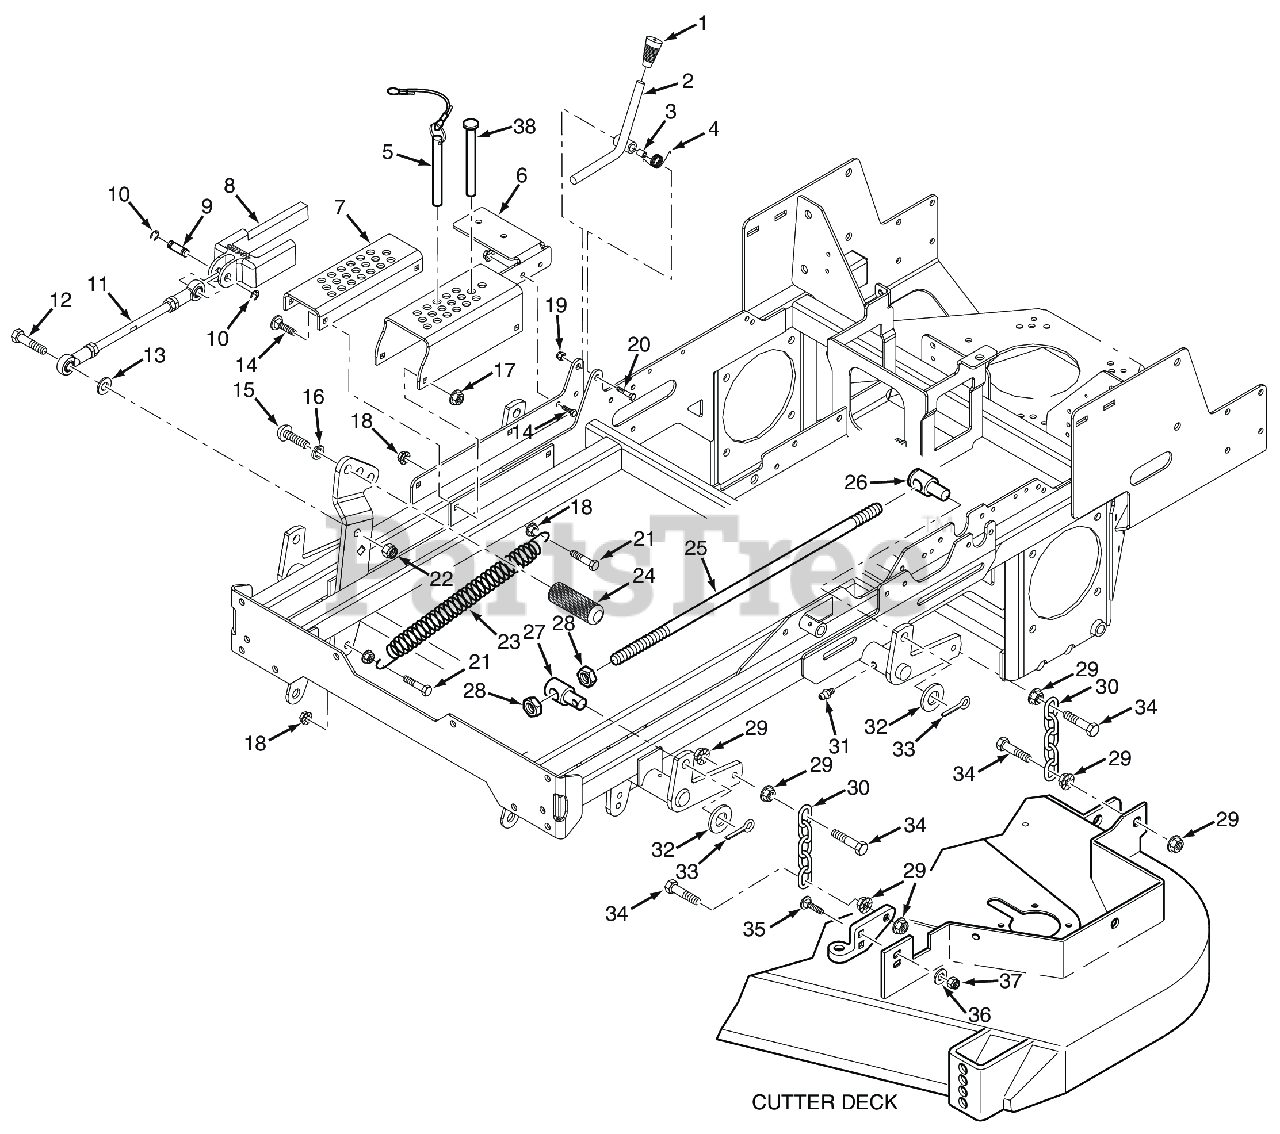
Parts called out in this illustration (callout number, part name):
1	Mounting Bracket, Fuel Tank
2	Deck Latch Assembly w/Grip
3	Bushing, .502 O.D.
4	Spring, Torsion - Lever Return
5	Lanyard, Deck Height Pin Assembly
6	Adjustment Bracket, Upper Cut Height
7	Adjustment Bracket, Lower Cut Height
8	Slide, Height Adjustment
9	Pin, Deck Lift
10	Retaining Ring, 1/2" External "E"
11	Linkage, Deck Lift
11	Rod End, 1/2-20 Female RH Thread
11	Rod End, 1/2-20 Female LH Thread
11	Nut, 1/2-20 UNF-2B RH Thread
11	Bolt, Hex Hd. 5/16-18 x 3-3/4"
12	Hex Head Bolt, 1/2-13 x 2"
13	Flatwasher, 1/2 - .531 x 1.062 x .095
14	Bolt, Heax Head 5/16-18 x 1" (48V / 52V)
14	Lockwasher, 5/16 (.317 x .586 x .078) Helical Spring
15	Bolt, Head Socket 5/8-11 x 1-1/2"
16	L o c kwasher, 1/2 Spring
17	Nut, Serrated Flange 5/16-18 (Right Front Engine Mounting, Briggs and Kohler Only)
18	NUT, 3/8-16 SERRATED FLANGE HEX HEAD
19	HEX NUT, ELASTIC STOP LOCK, 3/8-16
20	Capscrew, Hex Head 3/8-16 x 2.75"
21	Bolt, Hex Head 3/8-16 x 1-1/2" Grade 8 Black
22	HEX LOCKNUT, ELASTIC STOP, 1/2-13
23	Spring, Helper (61" & 72" Cutter Decks Only)
24	Foot Pedal, Height Adjustment
25	Stud, 5/8-11 x 22.0"
26	Swivel Joint, LH
27	Swivel Joint, RH
28	Hex Locknut, Elastic Stop, 3/8-16
29	NUT, 3/8-16 SERRATED FLANGE HEX HEAD
30	Chain, Deck Lift
31	GREASE FITTING, STR. 1/4-28 SELF TAP.
32	Flatwasher, 5/8" (.656 x 1.312 x .095")
33	Pin, Cotter 3/16 x 1.0"
34	Bolt, Hex Head, 3/8-16 x 1-1/2"
35	Bolt, Carriage 7/16-14 x 1-1/4"
36	Flatwasher, 7/16" (.500 x 1.25 x .083")
37	HEX LOCKNUT, ELASTIC STOP, 7/16-14
38	Pin, Locking
